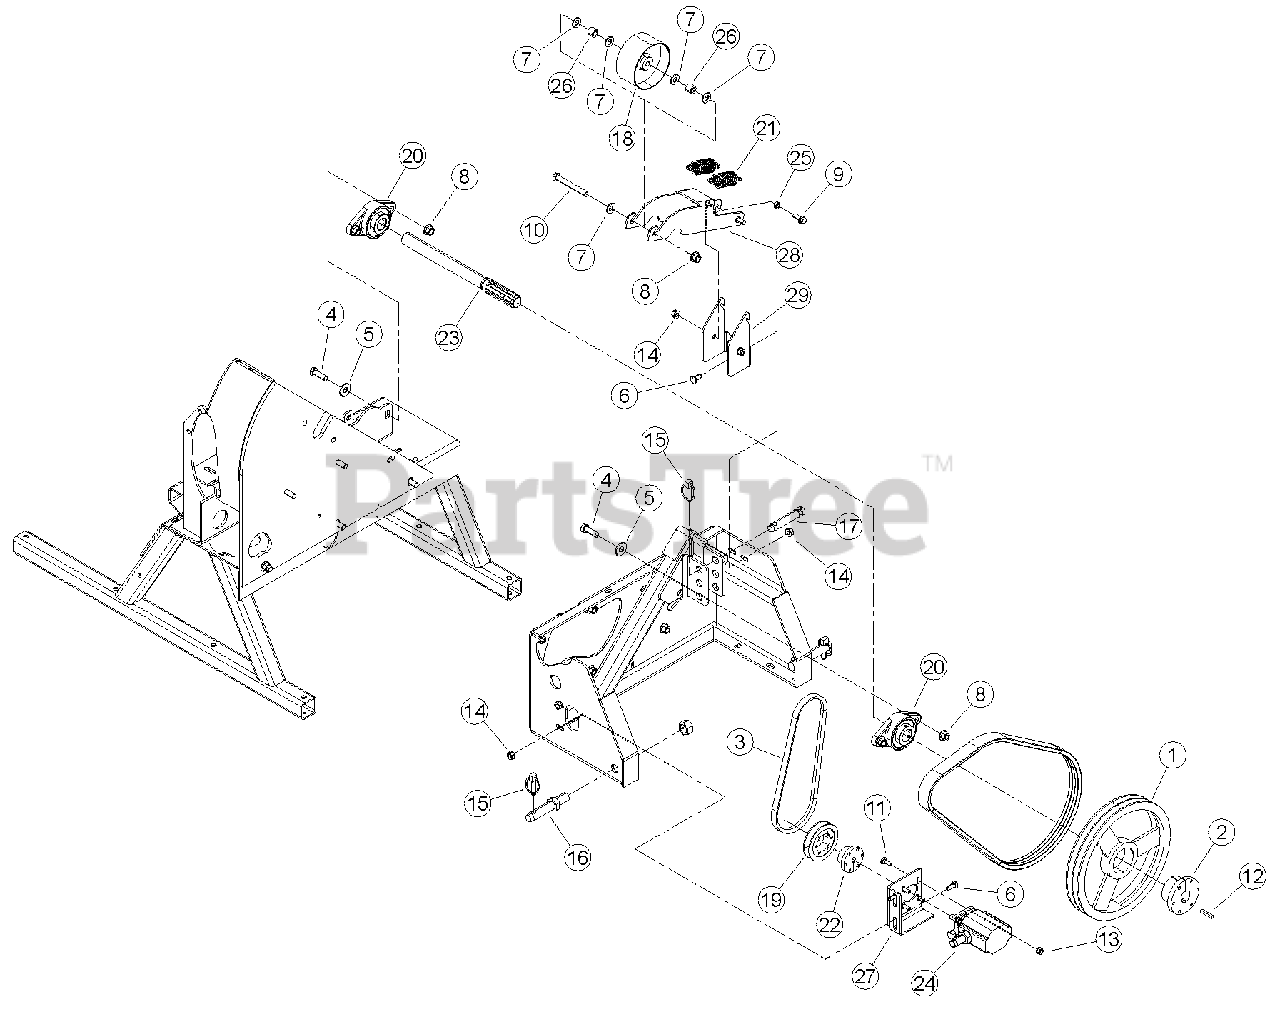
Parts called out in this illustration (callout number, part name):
1	SHEAVE, 2B12.4 SK
2	BUSHING, SK 1-1/4"
3	BELT, 4L350
4	BOLT, 1/2 X 1-1/2 HEX HD GR5 ZP
5	WASHER, 1/2" FLAT ZP
6	BOLT, 3/8 X 1" GR5 CRG NC ZP
7	WASHER, 1/2" SAE FLAT ZP
8	NUT, 1/2-13 NYLOCK FLANGE
9	BOLT, 3/8 X 1 FLANGE NC
10	BOLT, 1/2 X 4 HEX CPS G5 ZP
11	BOLT, 5/16 X 1" GR5 CRG ZP
12	KEY, 1/4 SQ X 1-1/2 LG PLAIN
13	NUT, 5/16-18 NYLOCK-FLANGE
14	NUT, 3/8-16 NYLOCK FLANGE
15	PIN, 7/16 X 1-3/4 LYNCH
16	PIN, LIFT ARM 7/8 X 5" LG
17	PIN, TOP LINK 3/4 X 4-1/2" LG
18	PULLEY, IDLER 5 X 2.50"
19	SHEAVE, 1B3.6 SH
20	BEARING, 1-1/4" DIA 2 BOLT FLANGE
21	SPRING, 1.25 OD X 3.50 LG X .148 WD
22	BUSHING, SH 1/2"
23	SHAFT, 6 SPLINE 5" CHIPPER
24	PUMP, 2 STAGE CW HI/LO 0.605 DISP.
25	SPACER, IDLER PIVOT
26	SPACER, .81 X .620
27	WELDMENT, PUMP MOUNT
28	ARM, INSIDE IDLER
29	BRACKET, INSIDE IDLER ARM MOUNTING
